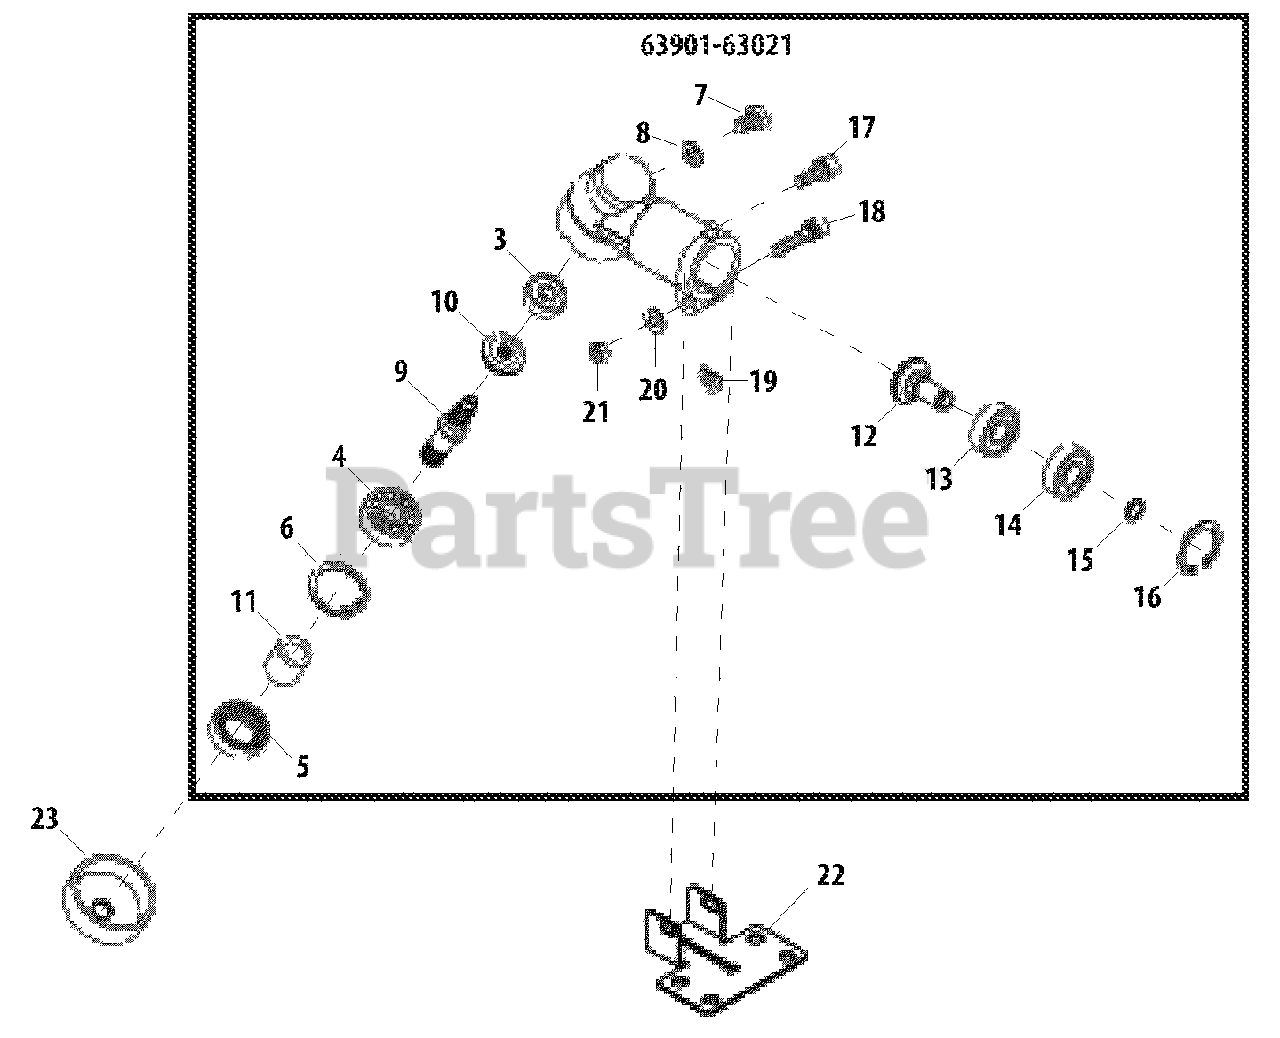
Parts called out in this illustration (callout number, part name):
3	BEARING, BALL - 626
4	BEARING, BALL - 6000
5	SEAL, OIL
6	RING, RETAINING - 26
7	BOLT - 6X10
8	WASHER
9	GEAR - SHAFT
10	GEAR - BEVEL
11	COLLAR
12	GEAR - SHAFT
13	BEARING, BALL - 608
14	BEARING, BALL - 608ZZ
15	RING, RETAINING
16	RING, RETAINING - 22
17	SCREW - 5X16
18	SCREW - 5X35
19	SHIM
20	WASHER - 5
22	CLAMP - LOWER
23	HOLDER
63901-63021	GEAR CASE ASSY
